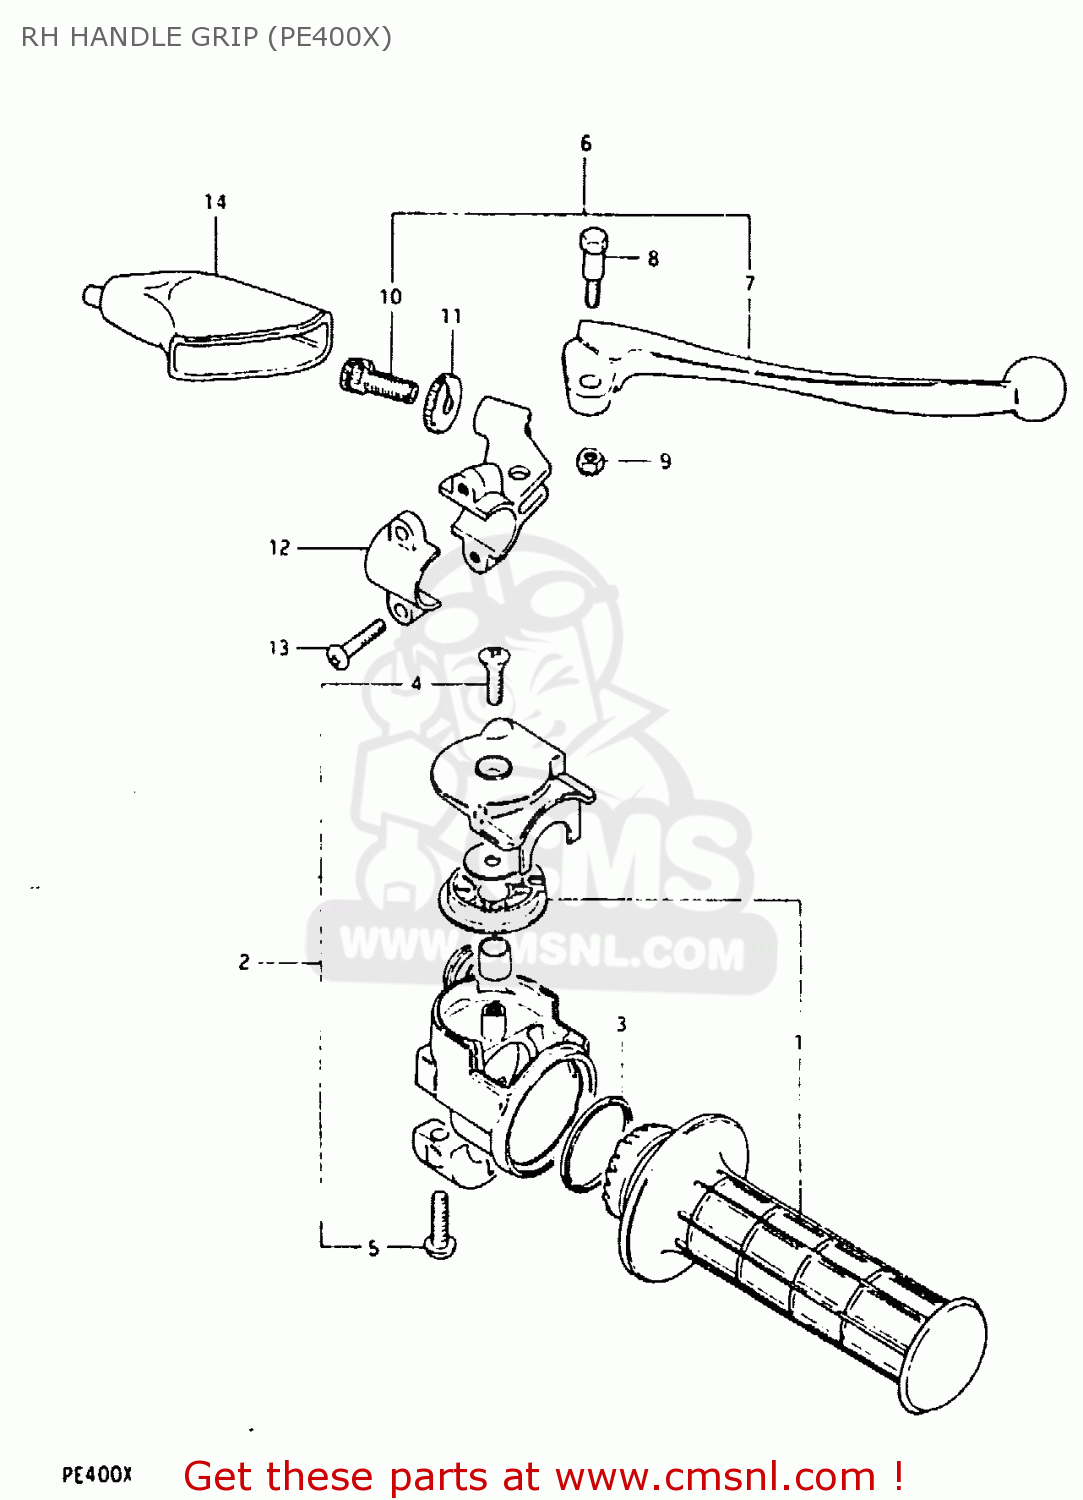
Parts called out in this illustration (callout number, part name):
1	GRIP SET,THROTTLE
2	CASE ASSY,THROTTLE
3	V-RING,THROTTLE GRIP
4	SCREW
5	SCREW 5X20
6	LEVER ASSEMBLY,BRAKE
7	LEVER,BRAKE
8	BOLT,LEVER
9	NUT 6MM
10	ADJUSTER,CABLE
11	NUT,CABLE ADJUSTER
12	BRACKET,LEVER
13	SCREW
14	COVER,CLUTCH LEVER
